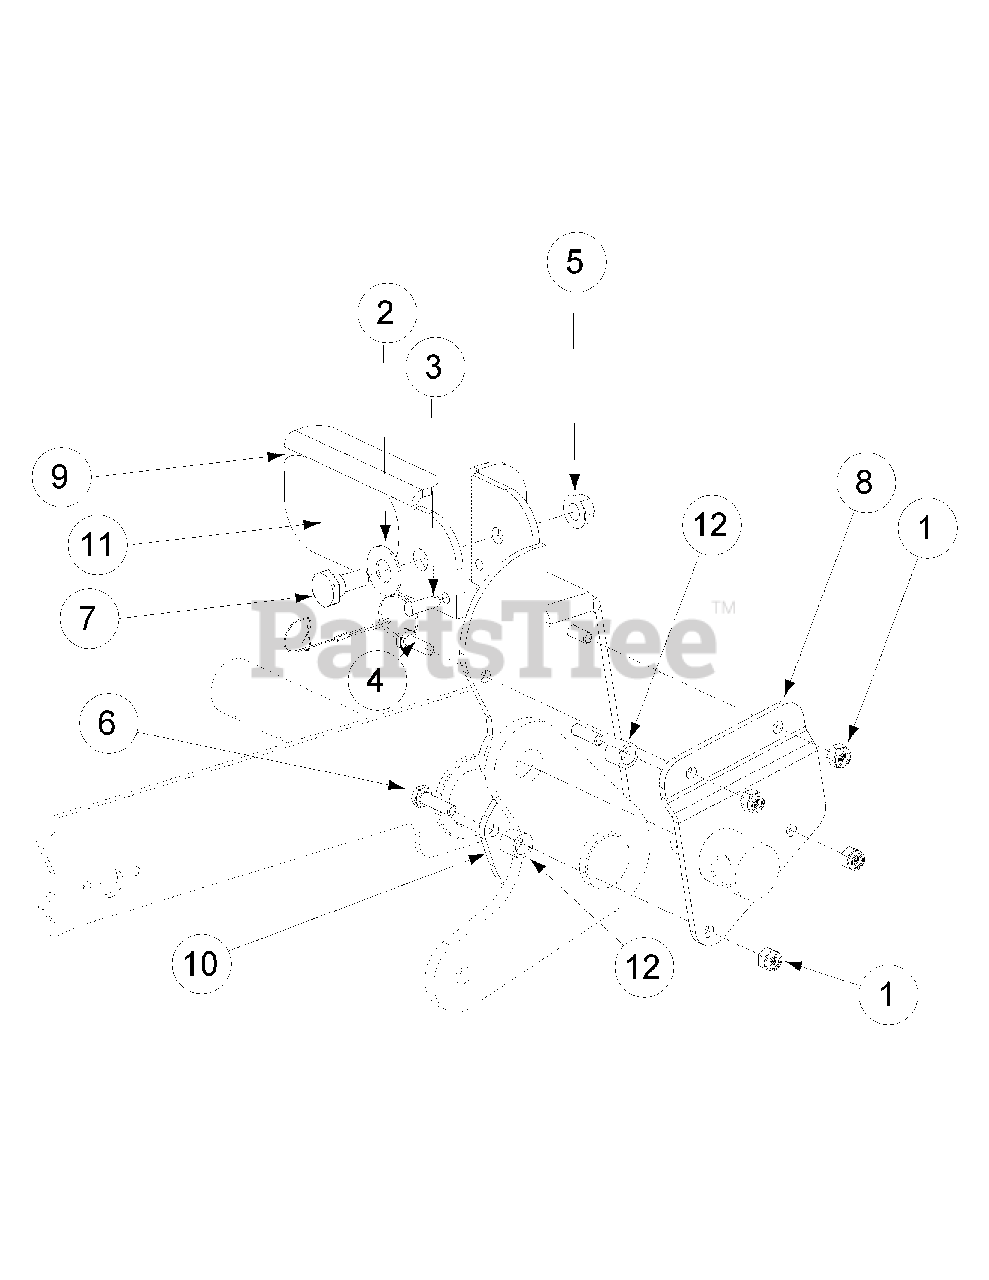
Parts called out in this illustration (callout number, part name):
1	Lock Nut, Nylon Insert, 1/4-20
2	Washer, 1/2 x 1 Shim
3	Detent Pin w/12" Lanyard
4	Hex Cap Screw, 1/4-20, .75
5	Hex Nut, Flange Lock 3/8-16
6	Hex Cap Screw, 1/4-20, 1.00
7	Shoulder Screw, .50 x .27 Lg., 3/8-16
8	Foot Lift Backup Pedal
9	Deck Lift Foot Pedal
10	Deck Lift Foot Pedal
11	Deck Lift Foot Pad
12	Turnbuckle Sleeve
